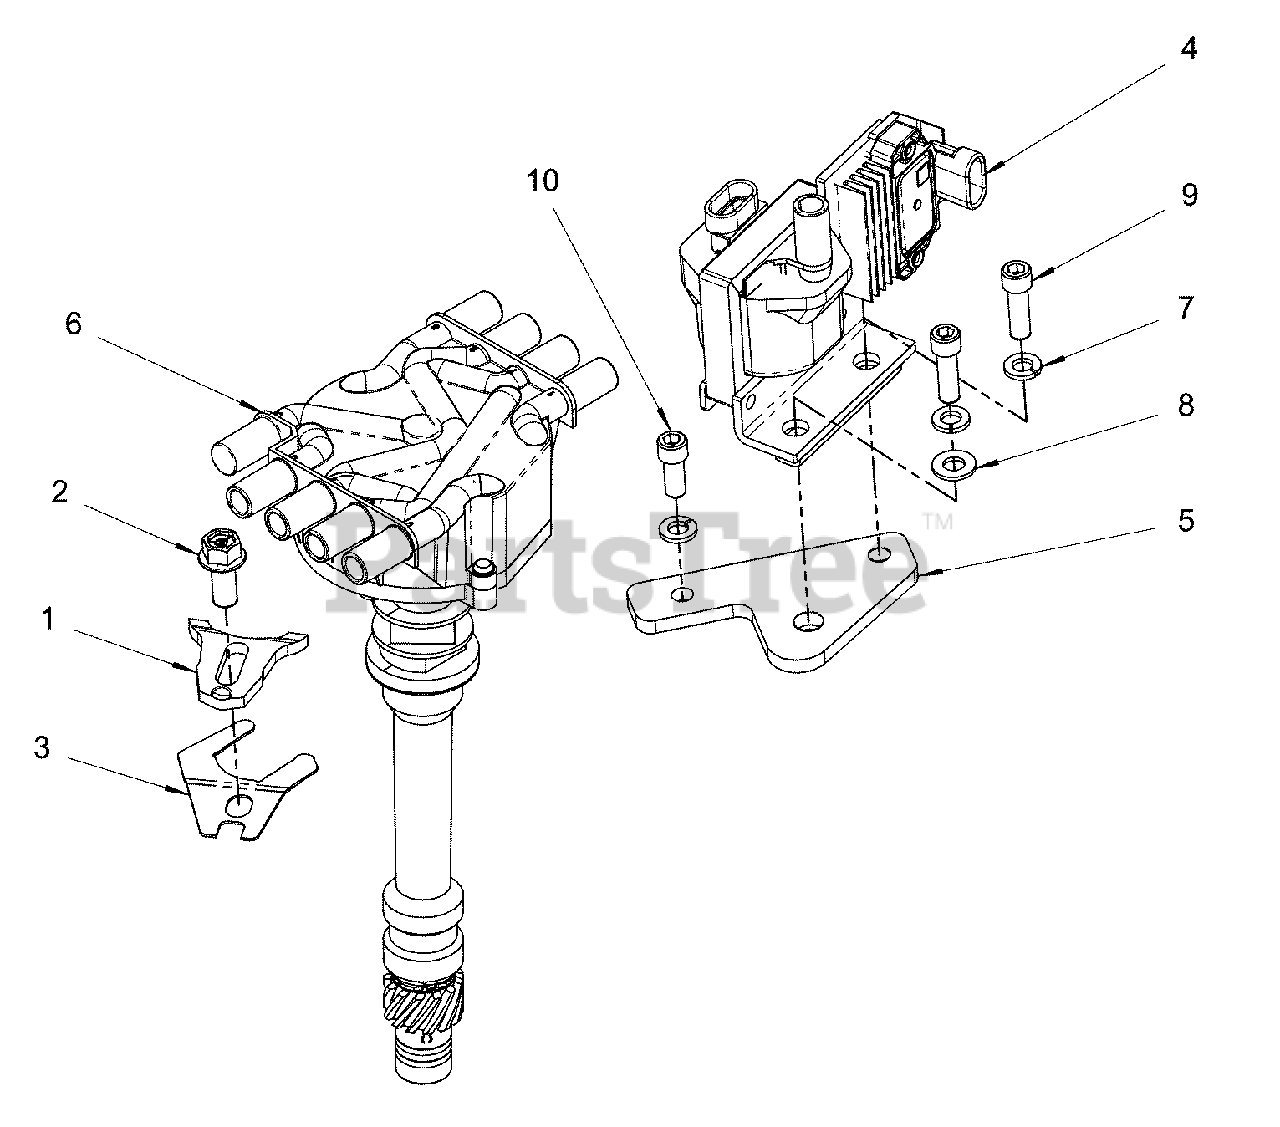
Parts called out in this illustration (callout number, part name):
1	* CLAMP
2	* BOLT
4	IGNITION COIL
5	* BRACKET
7	* WASHER
8	* WASHER
9	* BOLT
10	* BOLT
